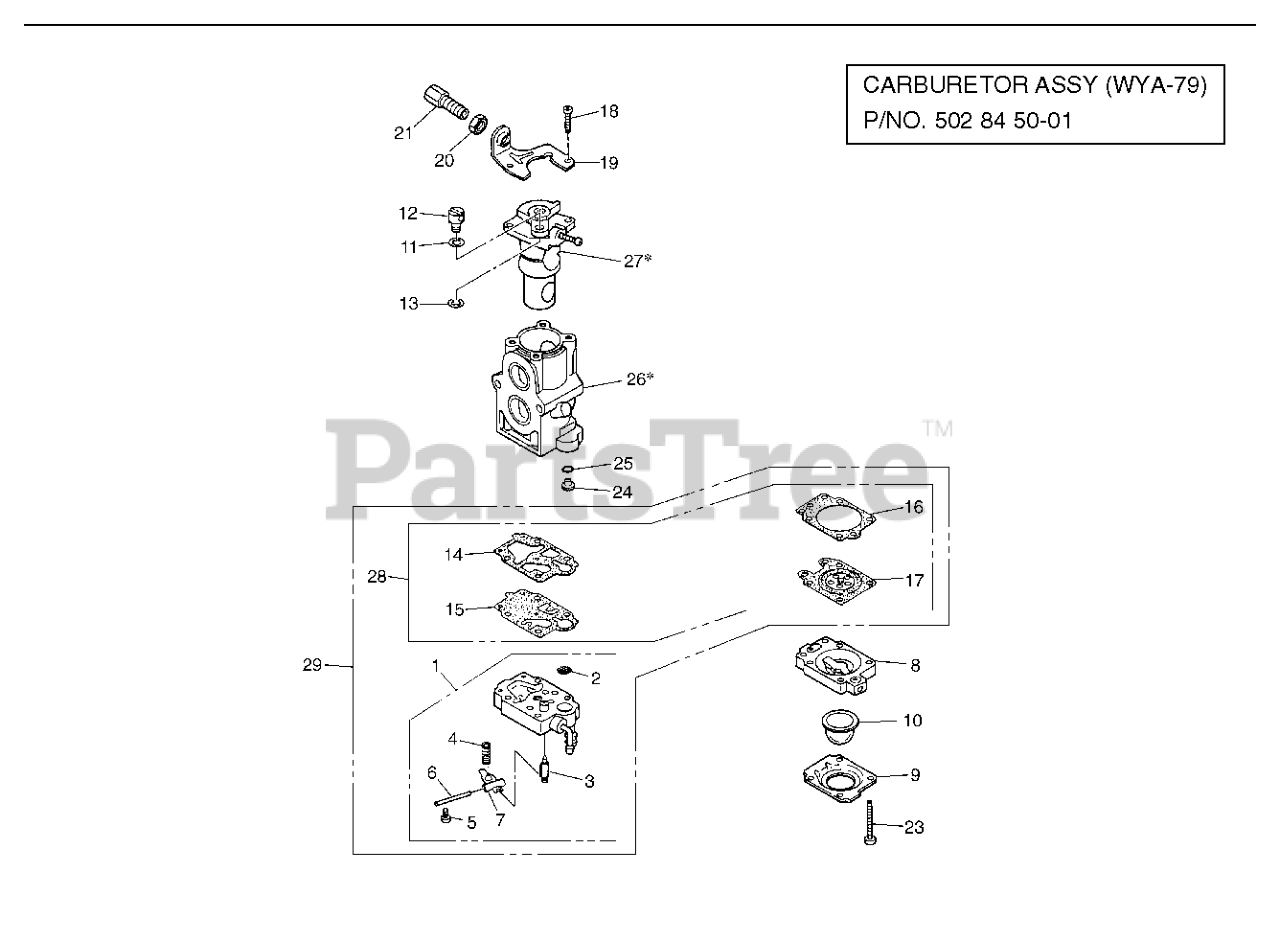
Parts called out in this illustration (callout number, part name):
1	BODY-A-PUMP
9	1OVER
11	WASHER
12	SWIVEL
13	RING
18	SCREW
19	BRACKET
20	NUT
21	ADJUSTER
24	JET (RPLS T104881250)
26	CARBURETOR
27	CARBURETOR
28	GASKET KIT
29	REBUILD KIT
